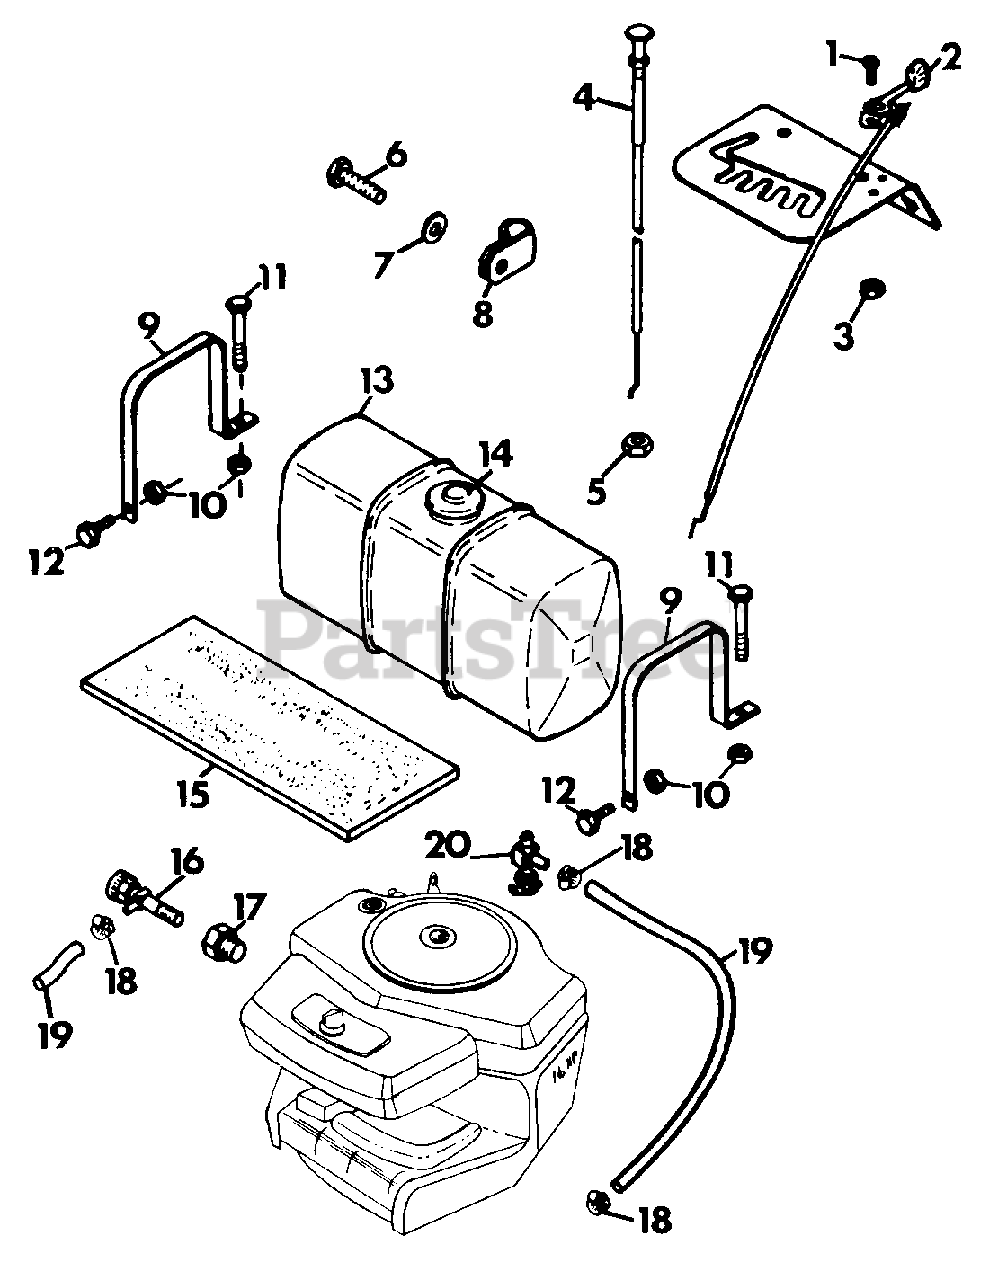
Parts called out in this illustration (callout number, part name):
1	KEY, IGNITION SWITCH
2	NUT, JAM 5/8-32
3	WASHER, LOCK 5/8 INT. TOOTH
4	SWITCH
5	SCREW, MACHINE 10-24X.75 PHD
6	WASHER, FLAT .188X.438X.049
7	NUT, STAMPED 9/16-18
8	BRACKET, INTERLOCK SWITCH
9	SWITCH, INTERLOCK
10	NUT, LOCK 10-24
11	HARNESS, WIRING SWITCH
12	HARNESS, WIRING INTERLOCK
13	TIE, CABLE
14	SWITCH, NEUTRAL START
15	TERMINAL, CONNECTOR CLIP TYPE
16	WASHER, LOCK NO. 10
17	SCREW, MACHINE 10-32X.50 PHD
18	CONTROL MODULE
19	SCREW, TAPPING 10-24X.50 HHD SF
